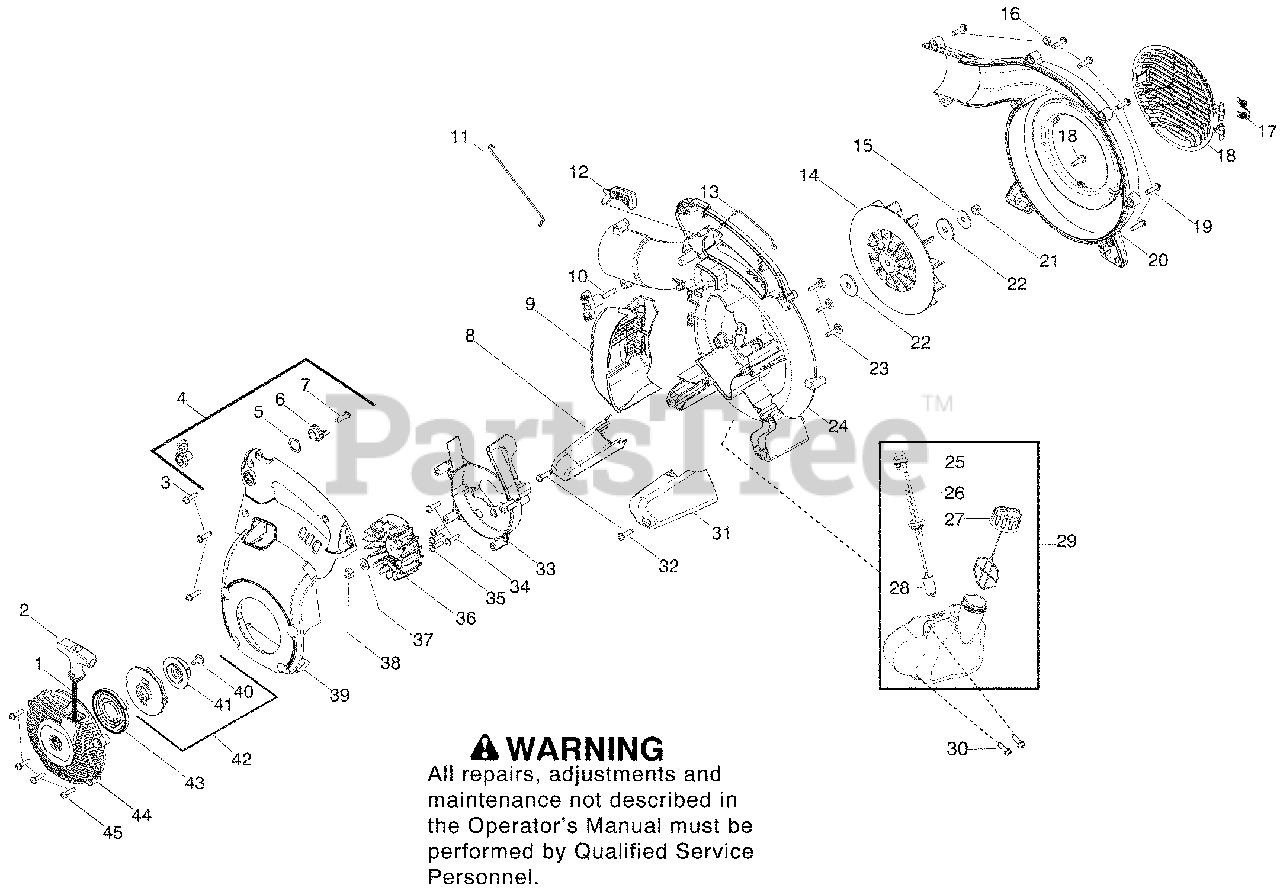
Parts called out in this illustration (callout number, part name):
1	Kit - Rope
2	Handle - Starter
4	Kit - Cruise Control
5	Washer - Wave
6	Ratchet - Cruise Control
8	Foot - Front Impact
9	Assy. - Muffler Guard
10	Assy - Blower Knob
11	Wire - Linkage
12	Trigger - Throttle
13	Wire - Handle Ground
14	Impeller
16	Nut - Blower Tube Knob
17	Spring - Vac Door
18	Cover - Vac Door
20	Assy - Outer scroll
21	Nut - Impeller
22	Washer - Impeller
24	Scroll - Inner
25	Bulb - Purge
26	Kit - Fuel line grommet
27	Assy - Fuel cap with retainer
28	Assy - Fuel pickup
29	Assy - Fuel tank
30	Screw - Fuel tank
31	Foot - Rear Impact
33	Scroll - Flywheel
35	Screw
36	Assy - Flywheel
38	Nut - Flywheel
39	Cover - Motor housing
42	Kit – Starter
43	Spring - Starter
44	Housing - Starter Cover
45	Screw
